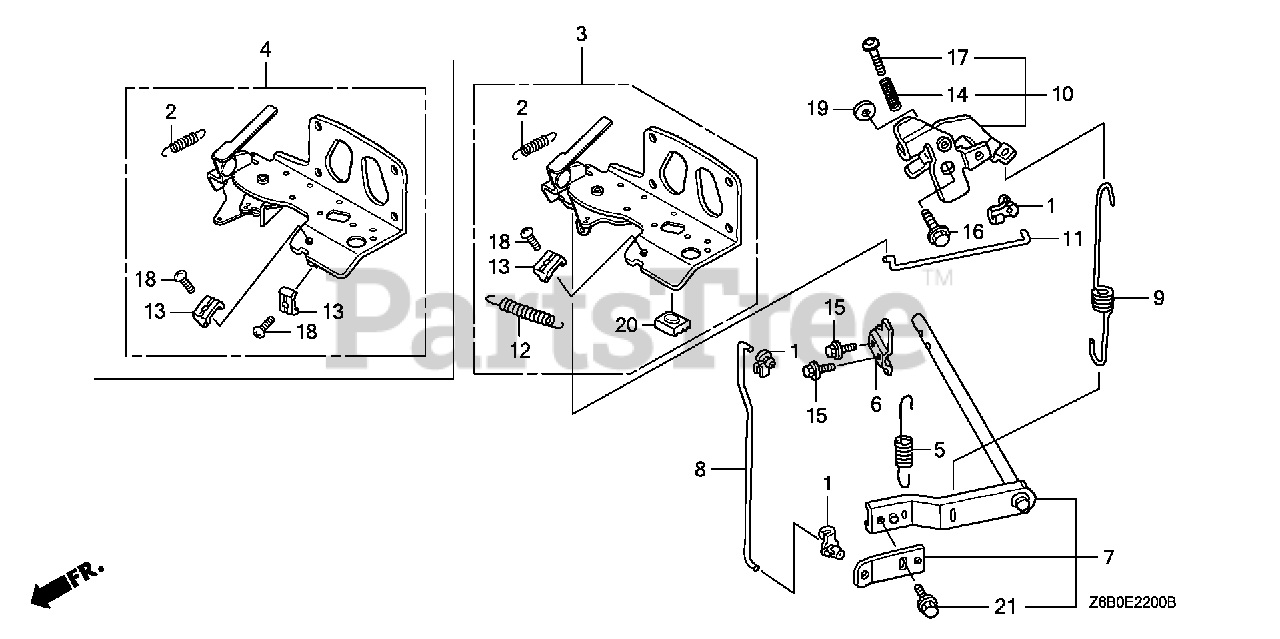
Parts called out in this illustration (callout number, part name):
1	ROD, JOINT
2	SPRING, CHOKE RETURN
4	CONTROL ASSY. (2-LEVER)
5	SPRING, STARTER
6	FORK, GOVERNOR
7	ARM, GOVERNOR
8	ROD, GOVERNOR
9	SPRING, GOVERNOR
10	LINK, GOVERNOR
11	ROD, GOVERNOR LINK
13	HOLDER, CABLE
14	SPRING, CONTROL ADJUSTING Use from Engine SN 2327377.
15	BOLT, FLANGE (5X10) Use from Engine SN 2327377.
16	BOLT, FLANGE (6MM) (CT200)
17	SCREW, RECESSED (5X25)
18	SCREW, PAN (5X16)
19	WASHER, PLAIN (6MM)
21	BOLT, FLANGE (6X10)
